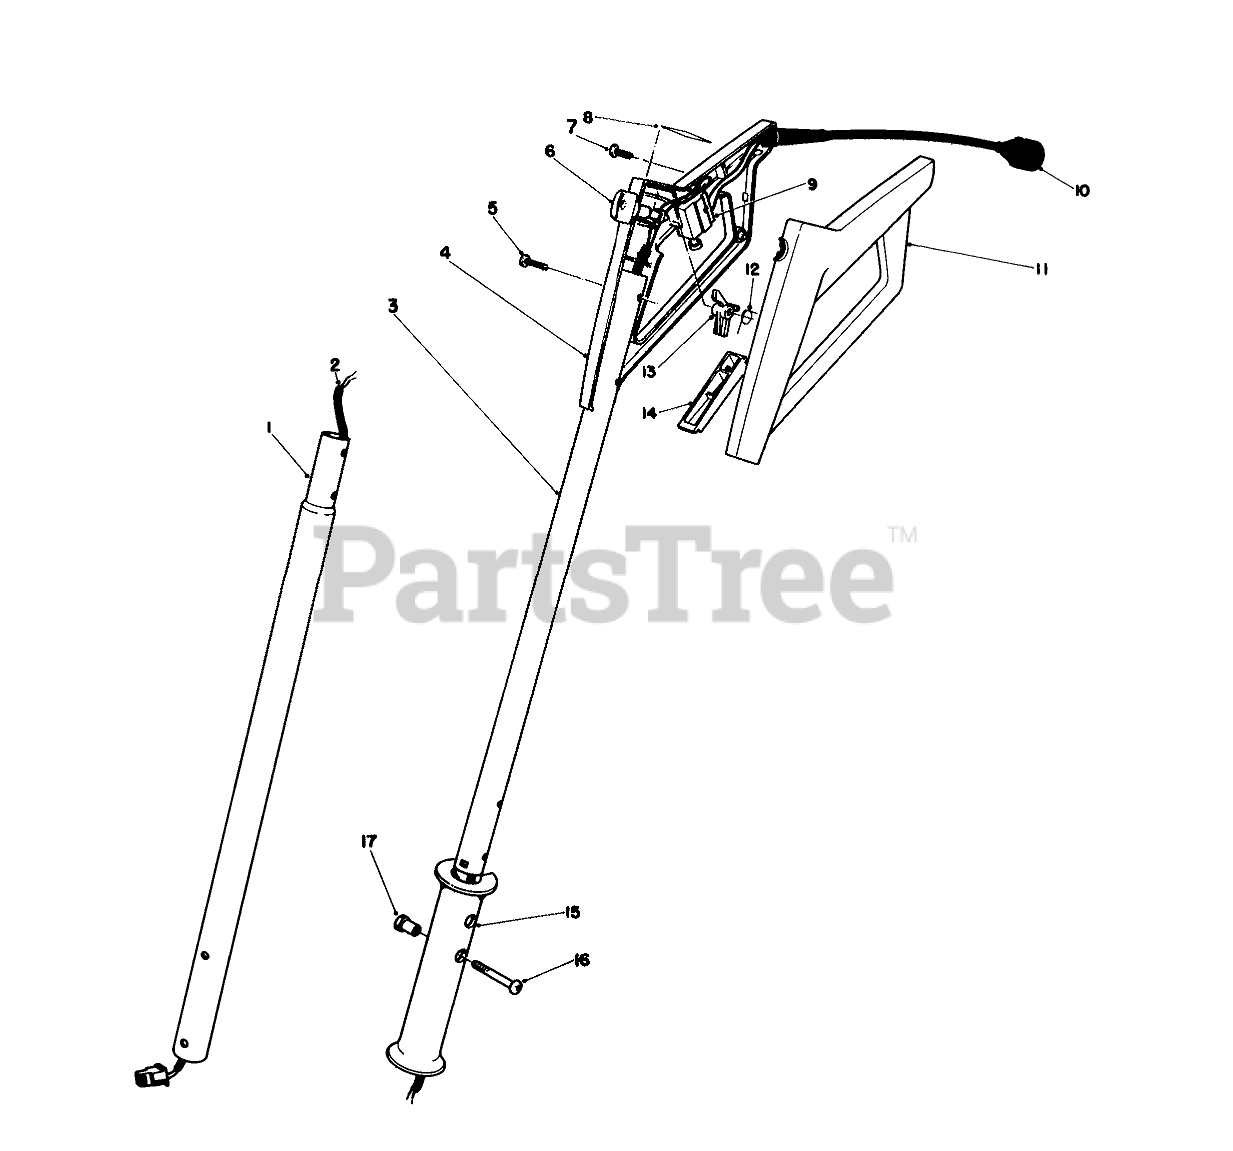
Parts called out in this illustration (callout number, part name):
1	LOWER TUBE, P. SHOVEL
2	Wire Harness
3	Tube-Upper Handle
4	Grip-Control R.H.
5	Screw
7	SCREW-PPH
8	UL GRIP DECAL
9	SWITCH-STARTER
10	Cord-Supply
11	Grip-Control L.H.
12	TORSION SPRING
13	LOCKOUT
14	SWITCH BAR,POWER SHOVEL
15	Grip-Handle
16	SPEC PAN HD SCREW
17	SPECIAL HEX NUT
